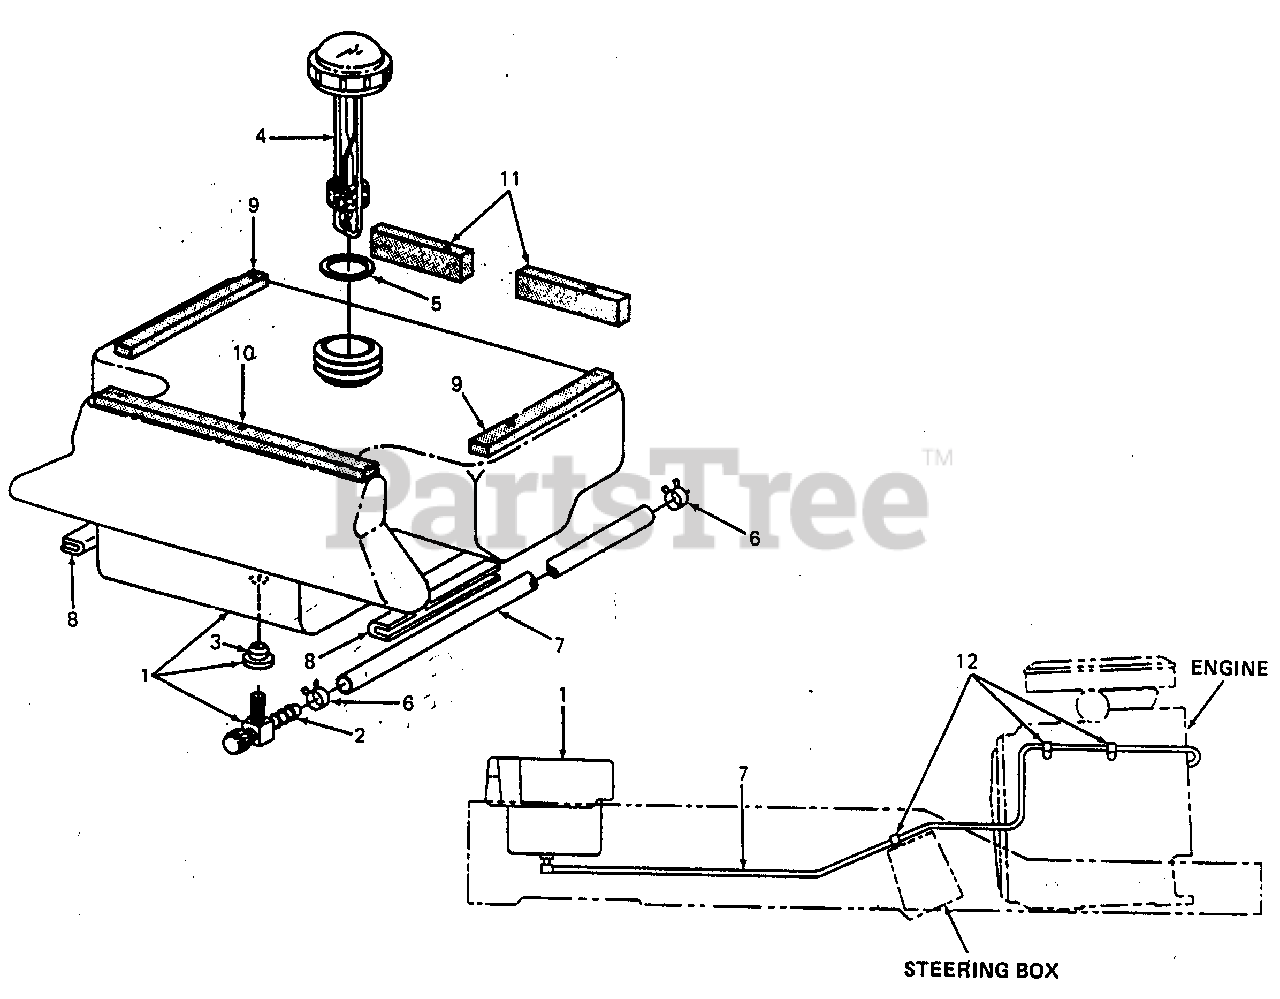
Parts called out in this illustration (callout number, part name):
1	Tank Assy, Fuel
2	Valve w/ Screen, Shut-off
3	Bushing
4	Cap w/ Gauge, Fuel Tank
5	Gasket, Fuel Tank Cap
6	Clamp, 1/2 O.D.Tube Hose
7	Line, Fuel, 65 in. Long
8	Seal, Edge, 4 in. Long
9	Strip, Foam Gasket Sealing, 5 in. Long
10	Strip, Foam Gasket Sealing, 12 in. Long
11	Strip, Foam Gasket Sealing, 3 in. Long
12	Clip
